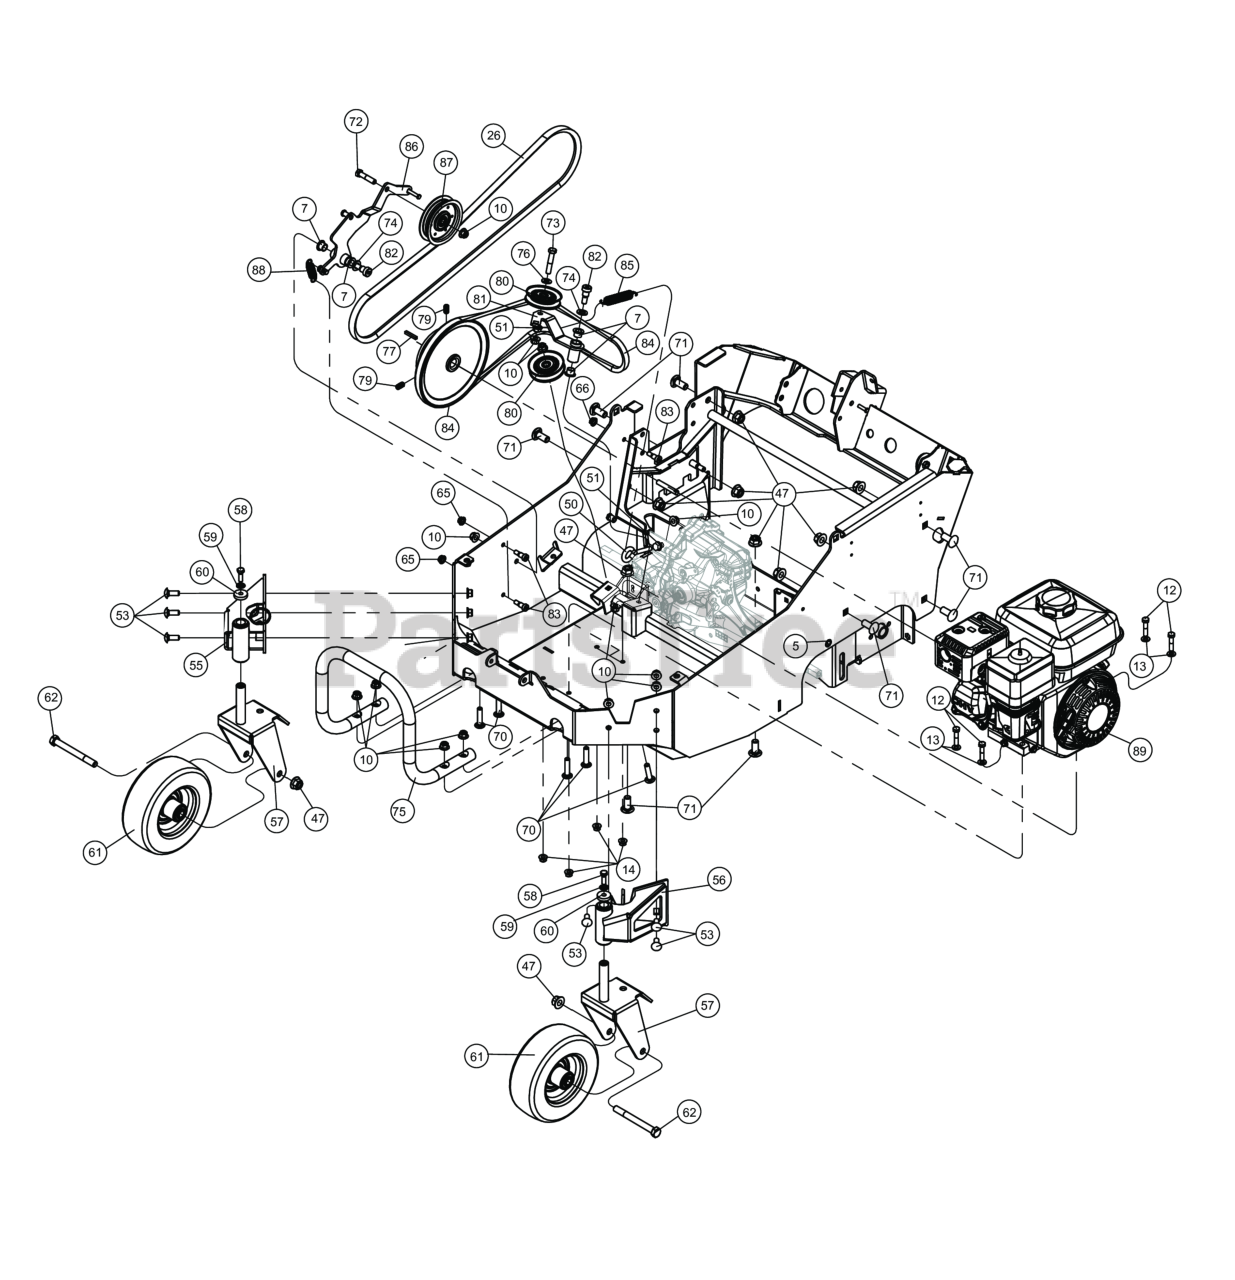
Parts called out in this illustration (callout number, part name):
7	BUSHING .500" ID
10	NUT-HEX-NYLK, FLG .375"-16 ZP
12	SCREWCAP 5/16"-18X1 1/2" HCS ZP
13	WASHER 5/16" SAE Z/P
14	NUT-HEX-NYLK, FLG .3125-18 ZP
26	BELT, V, 5L 61.82EL OHR ETH, AMD CD
47	NUT-HEX-NYLK, FLG .500"-13 ZP
50	BLT-HOOK, .375"-16 X 3.75" OAL W/NUT
51	NUT WASHER FACE
53	BOLT CARRAIGE 3/8-16 X 1" ZP
55	ASM, RH CASTER BRKT W/BUSHINGS & LOCK
56	ASM, LH CASTER BRKT W/BUSHINGS & LOCK
57	WA, CASTER WHEEL
58	SCREWCAP 5/16"-18 X 1" HCS ZP
59	WASHER, BELLEVILLE CONTACT .323X.717X.05
60	WASHER 1.125 OD X 0.344 ID X .25 THK ZP
61	WHEEL, 8" X 3" HEAVY DUTY
62	SCREWCAP 1/2"-13 X 4 3/4 HCS ZP GR. 5
65	NUT FLANGE 5/16"-18 ZP
70	BLT-RDHDSSQNK, .375"-16 X 1.750" G5 ZP
71	BLT-RDHDSSQNK, .500"-13 X 1.250" G5 ZP
72	SCREWCAP 3/8"-16 X 1 3/4" HCS ZP
73	SCREWCAP 3/8"-16X2" HCS ZP
74	WSHR-STL,FLT .500"X.875"X.0747" MAB ZP
75	GUARD, FRONT
76	WASHER 3/8"SAE 13/32"X13/16"X1/16"
77	KEY 3/16" SQ X 1 1/4"
79	SCREW SET 3/8-16 X 3/4 CUP POINT
80	PULLEY 3V GROOVE IDLER
81	WA, MULE DRIVE
82	BLT-SLDR,SH.500"X2.00",.375"-16X.63"G8ZP
83	BOLT SHOULDER, 3/8" DIA. X 3.25" LONG
84	BELT, V, 3V 53.00EL OHR CL, PLY CD
85	SPRING, EXT 4.090" X Ø.701 X 14LBF/IN
86	WA, IDLER ARM
87	PULLEY IDLER 4" OD X 3/8"
88	SPRING IDLER UPPER OS900SP
89	GX160 HONDA ENGINE W/GEARBOX
